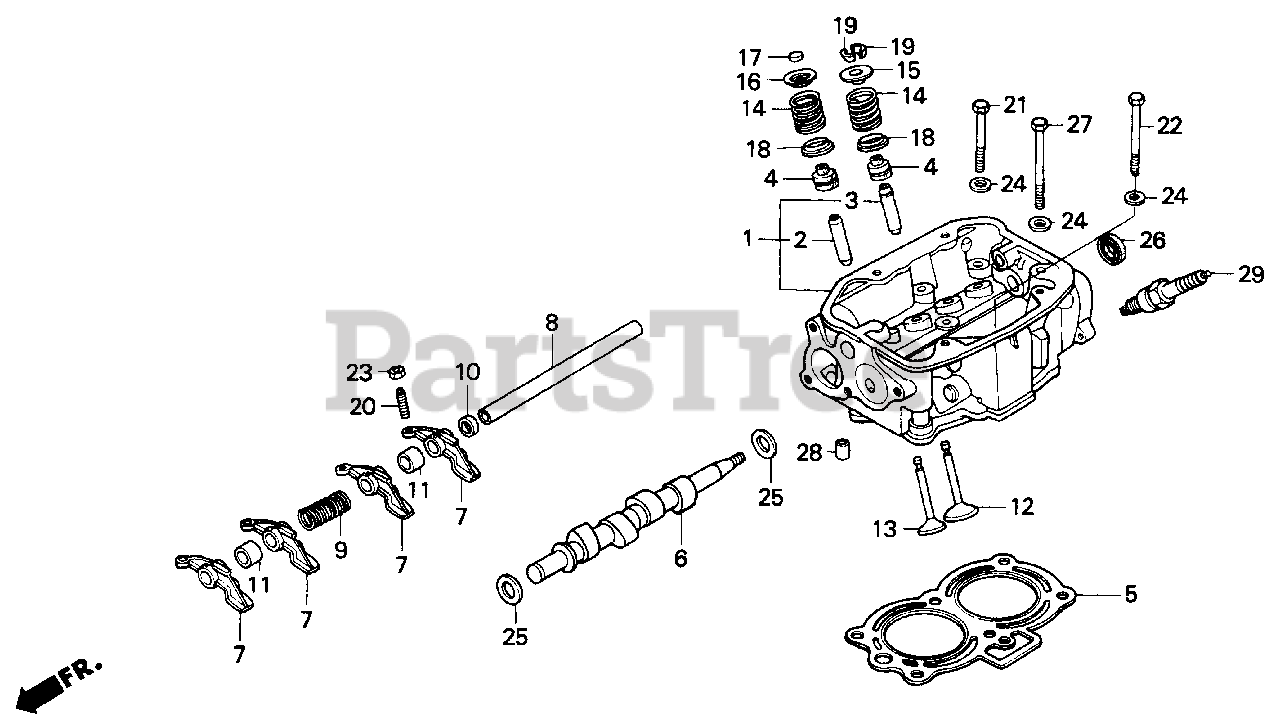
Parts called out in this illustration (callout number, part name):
1	CYLINDER HEAD
2	GUIDE, EX. VALVE
3	GUIDE, VALVE (OS)
4	SEAL, VALVE STEM
5	GASKET, CYLINDER HEAD
7	ARM, VALVE ROCKER
8	SHAFT, VALVE ROCKER ARM
9	SPRING, VALVE ROCKER ARM
10	COLLAR A, VALVE ROCKER ARM
11	COLLAR B, VALVE ROCKER ARM
12	VALVE, IN.
13	VALVE, EX.
14	SPRING, VALVE
15	RETAINER, VALVE SPRING
16	RETAINER, VALVE SPRING
17	ROTATOR, VALVE
18	SEAT, VALVE SPRING
19	COTTER, VALVE
20	SCREW, TAPPET ADJ.
21	BOLT, HEAD (8X70)
22	BOLT, HEX. (8X55)
23	NUT, TAPPET ADJ.
24	WASHER, HEAD (8MM)
25	WASHER, THRUST (16MM)
26	OIL SEAL (16X28X6)
27	BOLT, HEX. (8X100)
28	PIN A, DOWEL (10X16)
29	SPARK PLUG (BPR4HS) (NGK)
29	SPARK PLUG (BPR5HS) (NGK)
